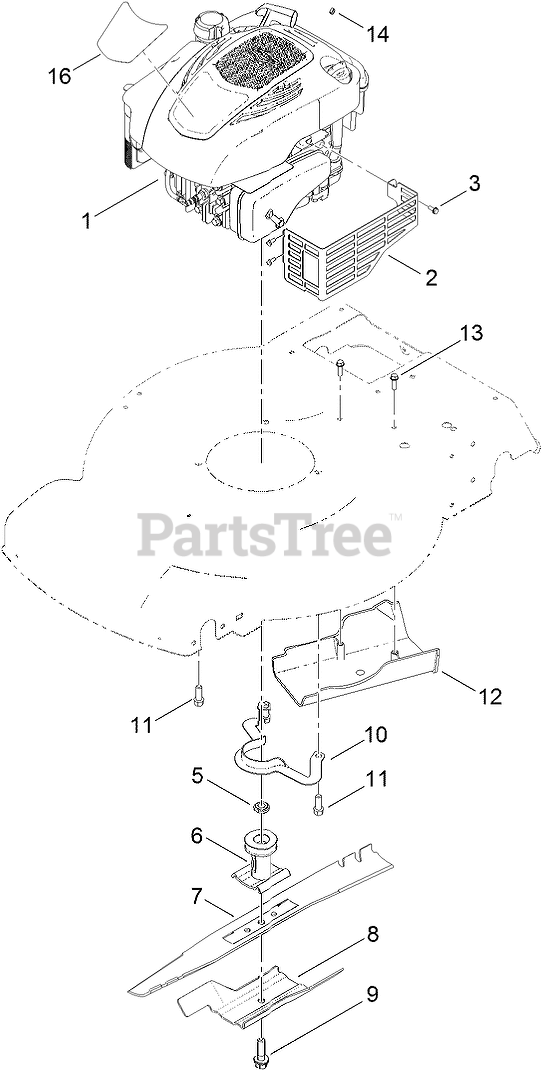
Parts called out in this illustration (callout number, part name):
2	SHIELD-MUFFLER
3	SCREW-TAPTITE
5	Spacer-Driver
6	DRIVER-BLADE
7	BLADE
8	Accelerator-Blade
9	BOLT-BLADE
10	Guide-Belt
11	SCREW-TAPTITE
12	COVER-BELT
13	SCREW-HWH
14	STOP-ROPE
16	DECAL-SHROUD
